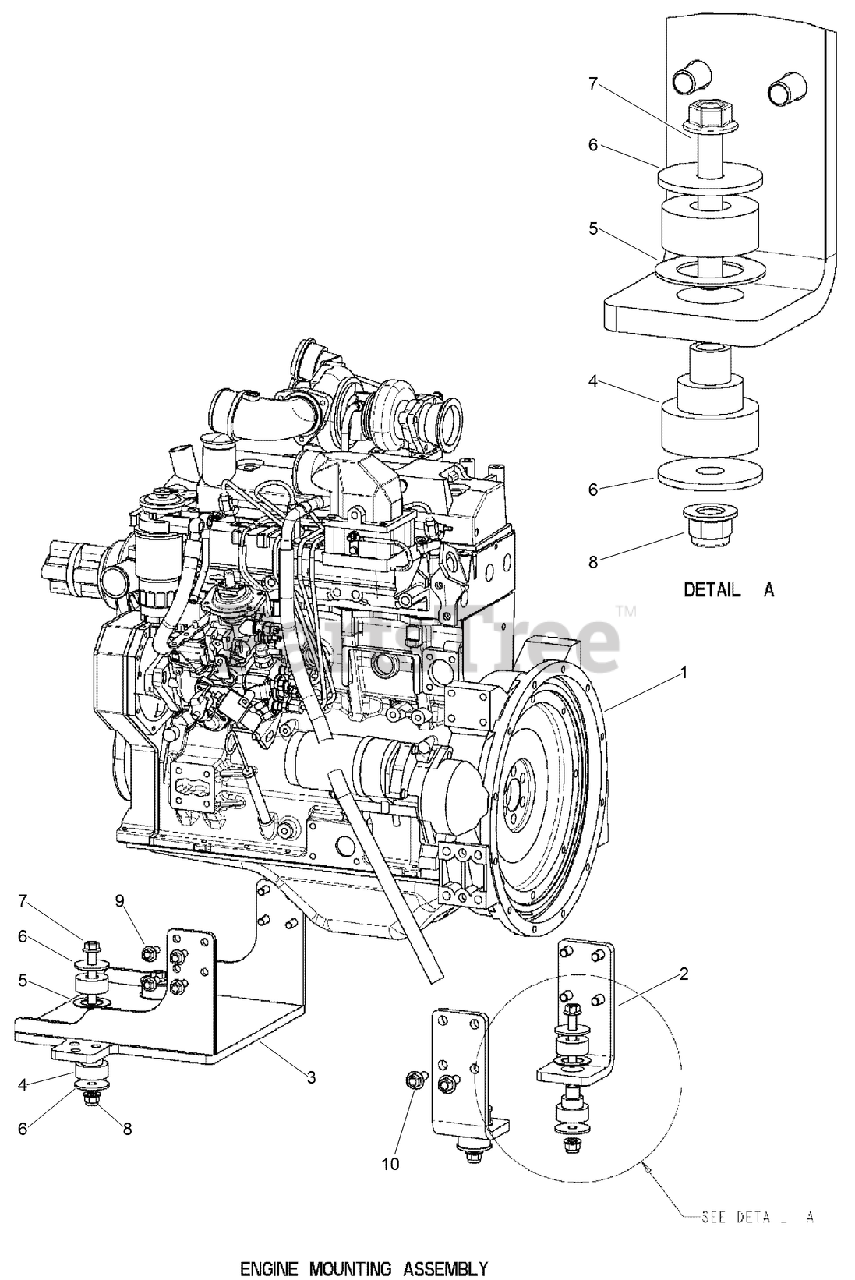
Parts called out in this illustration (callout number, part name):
1	ENGINE - Cummings D783007CX03 B3.3, 85 HP Tier 3
2	MOUNT - Engine, Rear
3	ASSEMBLY - Engine/Radiator Mount
4	ISOLATOR-MOUNTING, UNIVERSAL
5	SPACER-ISOLATOR
6	WASHER-FLAT
7	SCREW-HHF
8	NUT-HHF, LOCK
9	SCREW-FLANGE
10	SCREW, METRIC FLANGE w/BODY-M12 x 30
